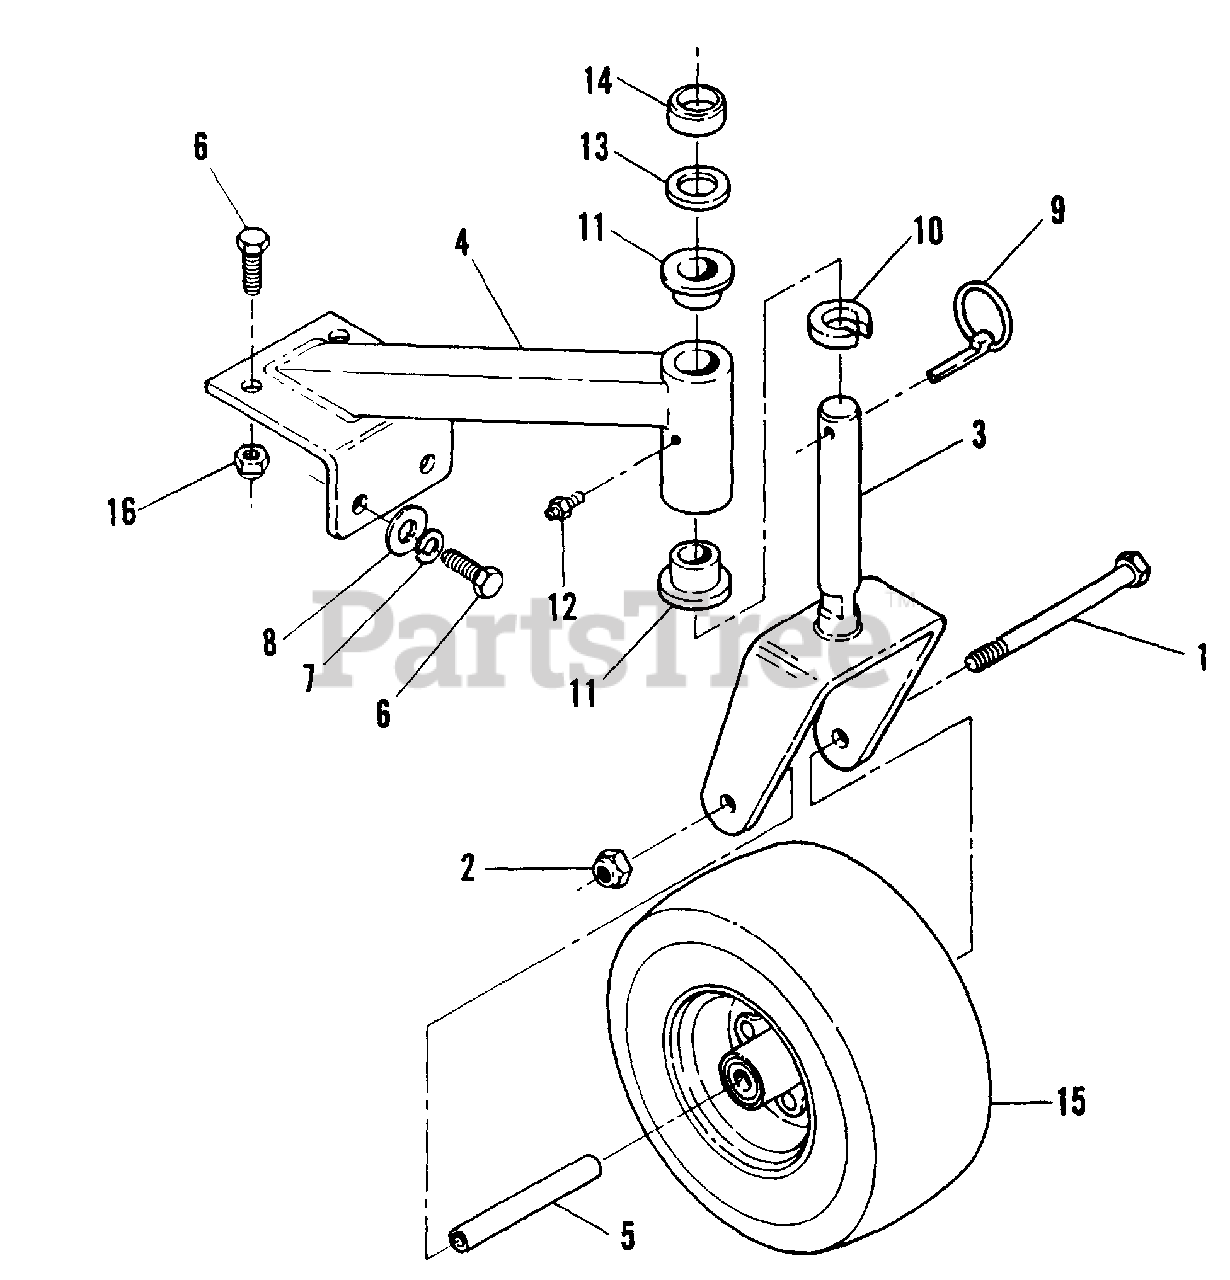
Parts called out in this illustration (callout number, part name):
1	BOLT, 1/2" x 5 1/2"
2	NUT, 1/2" Nyloc
3	YOKE, Caster, Weldment
4	CASTER SUPPORT ASSEMBLY
5	SLEEVE, Axle
6	SCREW, 3/8" C x 1", Gr. 5
7	WASHER, 3/8" Lock
8	WASHER, 3/8" Flat
9	PIN, Lynch
10	SPACER
11	BUSHING, Caster
12	ZERK, 1/8" NPT Straight
13	SPACER
14	SPACER, 1" x 1 3/8 x .30" (PM)
15	WHEEL & TIRE ASSEMBLY
16	NUT, 3/8" Nyloc
